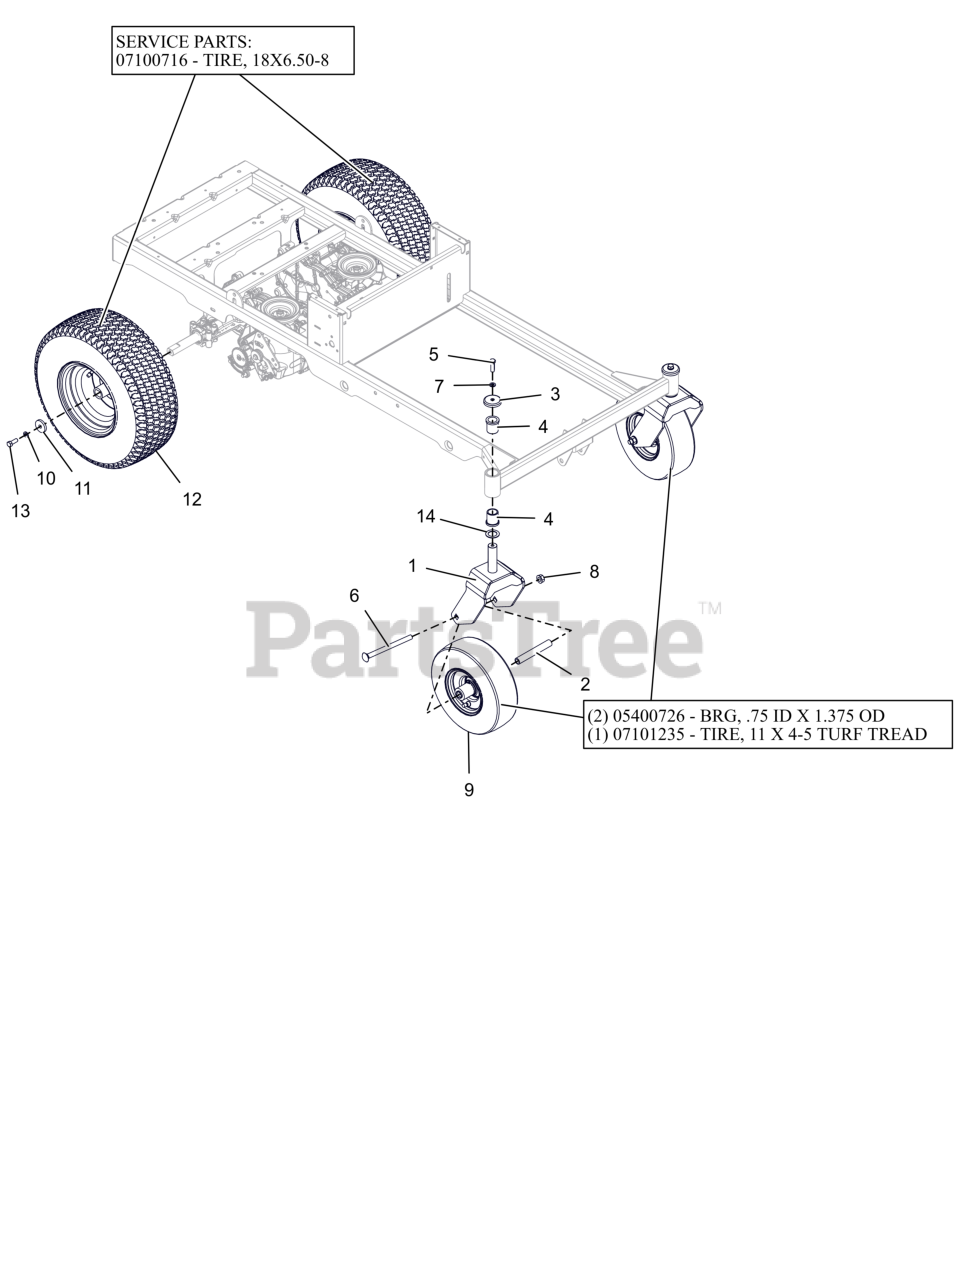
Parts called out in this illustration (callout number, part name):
1	WLDMT, CASTER FORK-X (ORANGE)
2	SPACER, ROLLED WHEEL
3	SHIELD, AXLE BEARING
4	BSHG-FLG 1.00X1.25X1.50X1.50
5	BLT, HEX .38-16X1.25 G5 ZCC
6	BLT, RHSN .50-13X6.50 G5 ZCC
7	WSHR,LK-REG .375X.094 ZCC
8	NUT-LK-CTR-FLG .500-13 GG ZCC
9	ASM, WHL/TIRE 11X4.00-5
9	BRG, .75 ID X 1.375 OD
9	TIRE, 11X4-5 TURF TREAD
9	TUBE 11 X4.0-5
10	WSHR,LK-REG .375X.094 ZCC
11	WSHR, FLT .406X1.50X.245 ZCC
12	ASM, WHL/TIRE 18X6.50-8 DHUB
12	TIRE, 18X6.5-8
13	BLT, HEX .38-16X1.00 G8ZCCEP30
14	WSHR-HRD-THRS 1.007X1.542X.062
